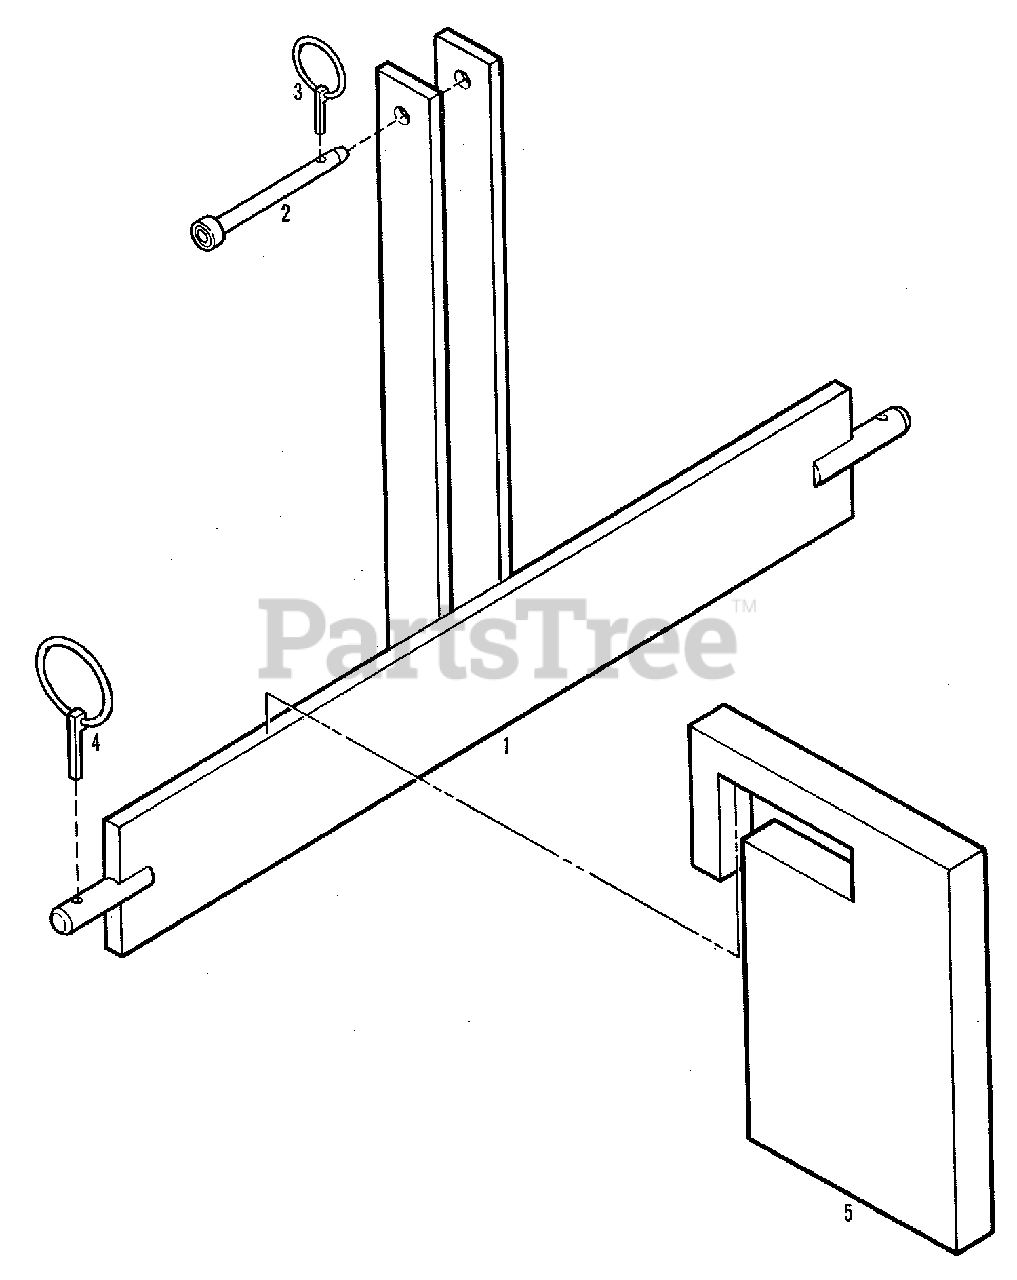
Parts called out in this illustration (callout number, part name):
1	SUPPORT ASSEMBLY, Weight
2	PIN, Attaching, Upper
3	PIN, Quick, Special Duty
4	PIN, Quick, Lower Attaching
5	WEIGHT, Suitcase
